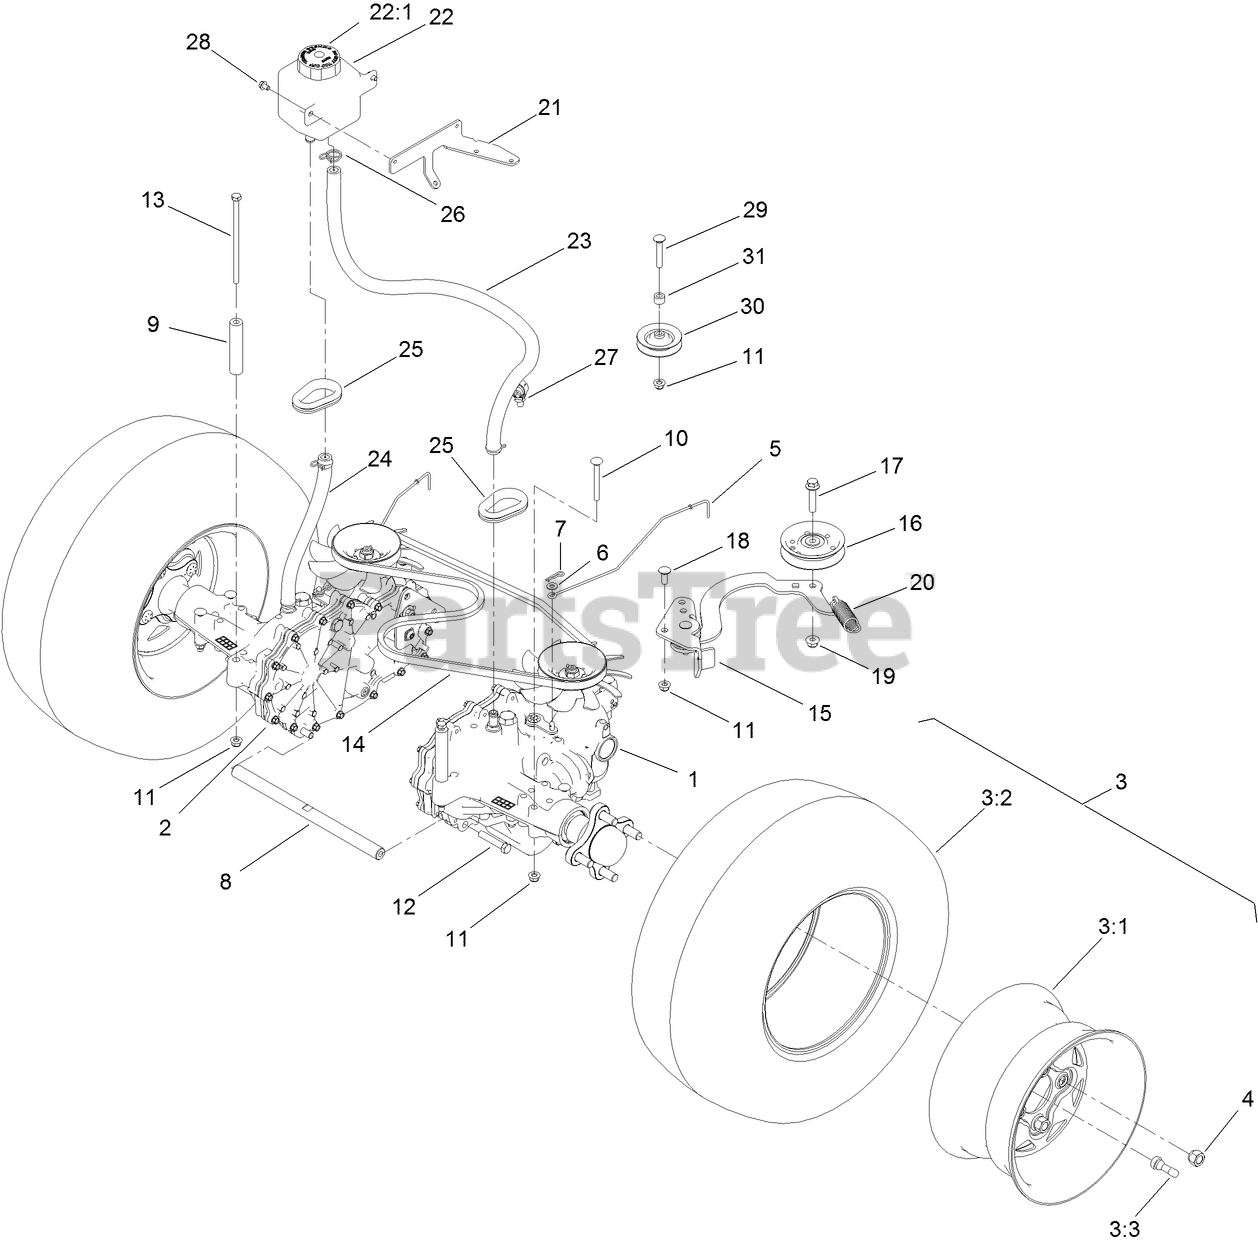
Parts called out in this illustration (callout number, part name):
1	TRANSMISSION, ZT-2800 LH
2	TRANSMISSION, ZT-2800 RH
3	WHEEL AND TIRE ASM
3:1	RIM-10"
4	NUT-LUG
5	ROD-BYPASS
6	WASHER-FLAT
7	PIN-COTTER
8	SHAFT-CROSS, HYDRO
9	SPACER - TRANSMISSION
10	SCREW-CARR
11	NUT-HF, NI
12	SCREW-HH W/LOCTITE
13	SCREW-HH
14	BELT-V
15	IDLER ARM ASM
16	PULLEY-IDLER, FLAT
17	SCREW-HHF
18	BOLT-CARR
19	NUT-HF, NI
20	SPRING-EXTENSION
21	BRACKET - EXPANSION TANK
22	TANK-HYD
22:1	CAP-RESERVOIR, HYD
23	HOSE-HYDRO
24	HOSE-OVERFLOW
25	GROMMET
26	CLAMP-HOSE
27	CLIP-TIE
28	SCREW-HWH
29	BOLT-CARR
30	PULLEY-IDLER
31	SPACER
